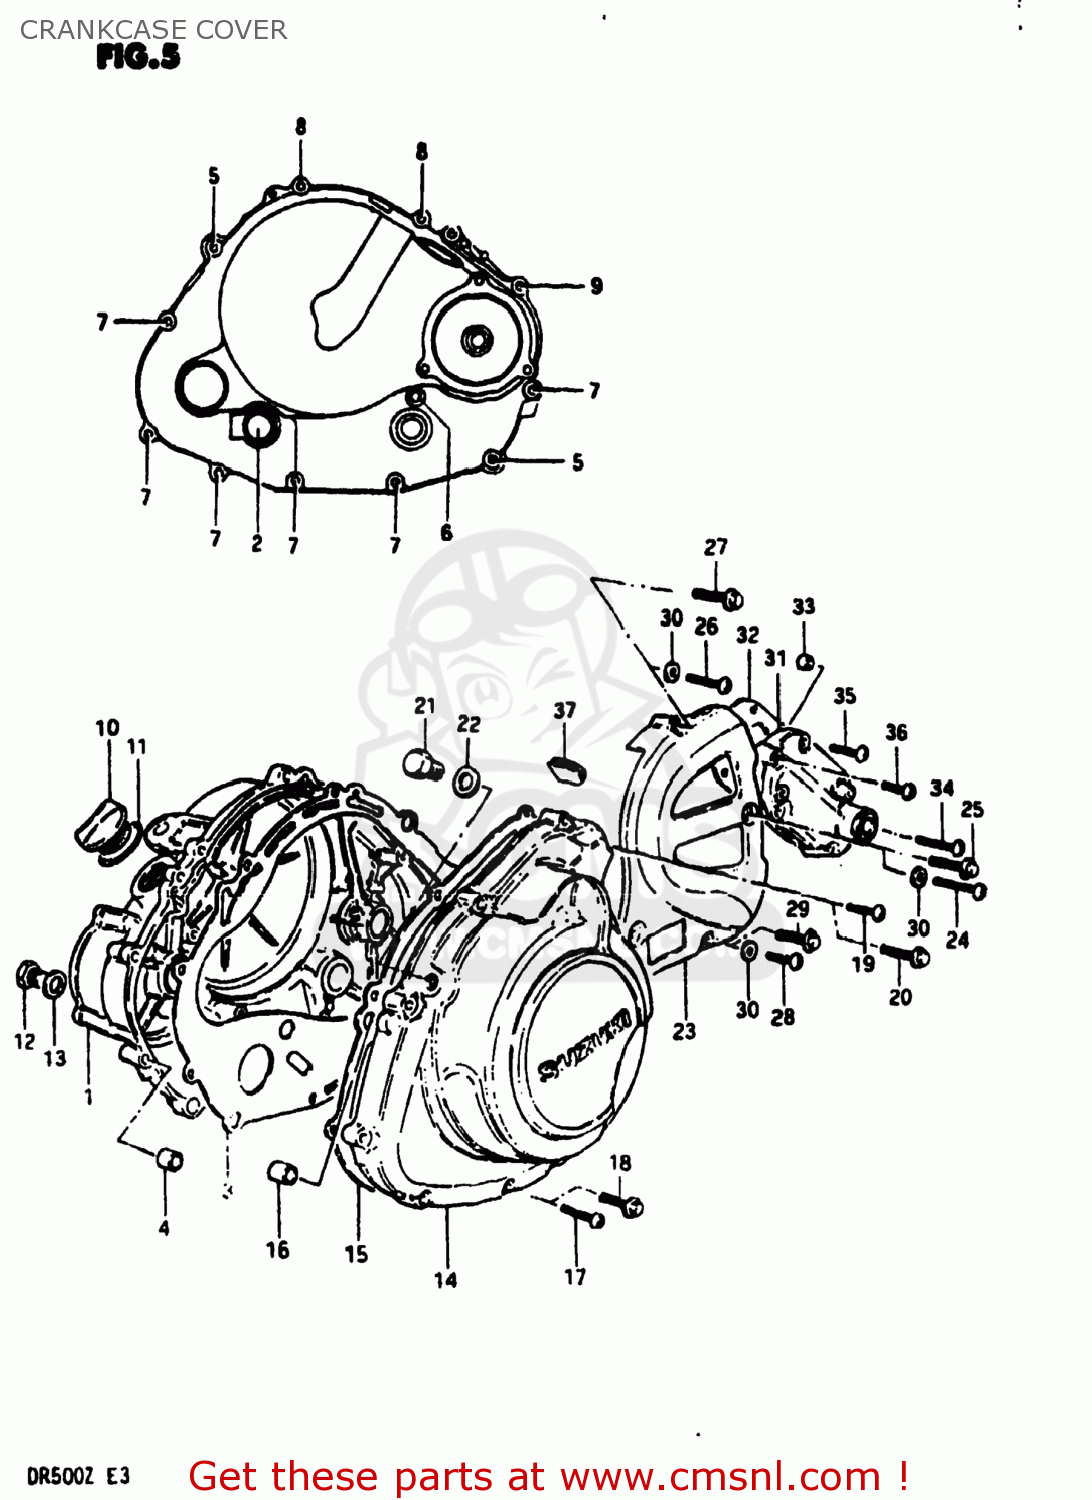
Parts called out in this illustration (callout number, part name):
1	COVER,CLUTCH
2	LENS,OIL LEVEL CHECK
3	GASKET,CLUTCH COVER (MCA)
4	PIN
5	SCREW
6	SCREW
7	BOLT (6X35)
8	BOLT
9	SCREW(6X25)
10	CAP
11	O RING(D:2.2,ID:32)
12	PLUG (14X12)
13	GASKET(14X19.2X2) (NAS)
14	COVER
15	GASKET,MAGNETO COVER (MCA)
16	PIN
17	SCREW 6X30
18	BOLT (6X30)
19	SCREW
20	BOLT
21	PLUG(12X9)
22	GASKET(12X16X2) (NAS)
23	COVER,SPROCKET
24	SCREW (6X45)
25	BOLT
26	SCREW 6X30
27	BOLT (6X30)
28	SCREW
29	BOLT (6X20)
30	WASHER
31	COVER,GEAR SHIFT
32	CUSHION,ENGINE SPROCKET
33	PIN
34	SCREW (6X35)
35	SCREW 6X30
36	SCREW
37	PLUG
